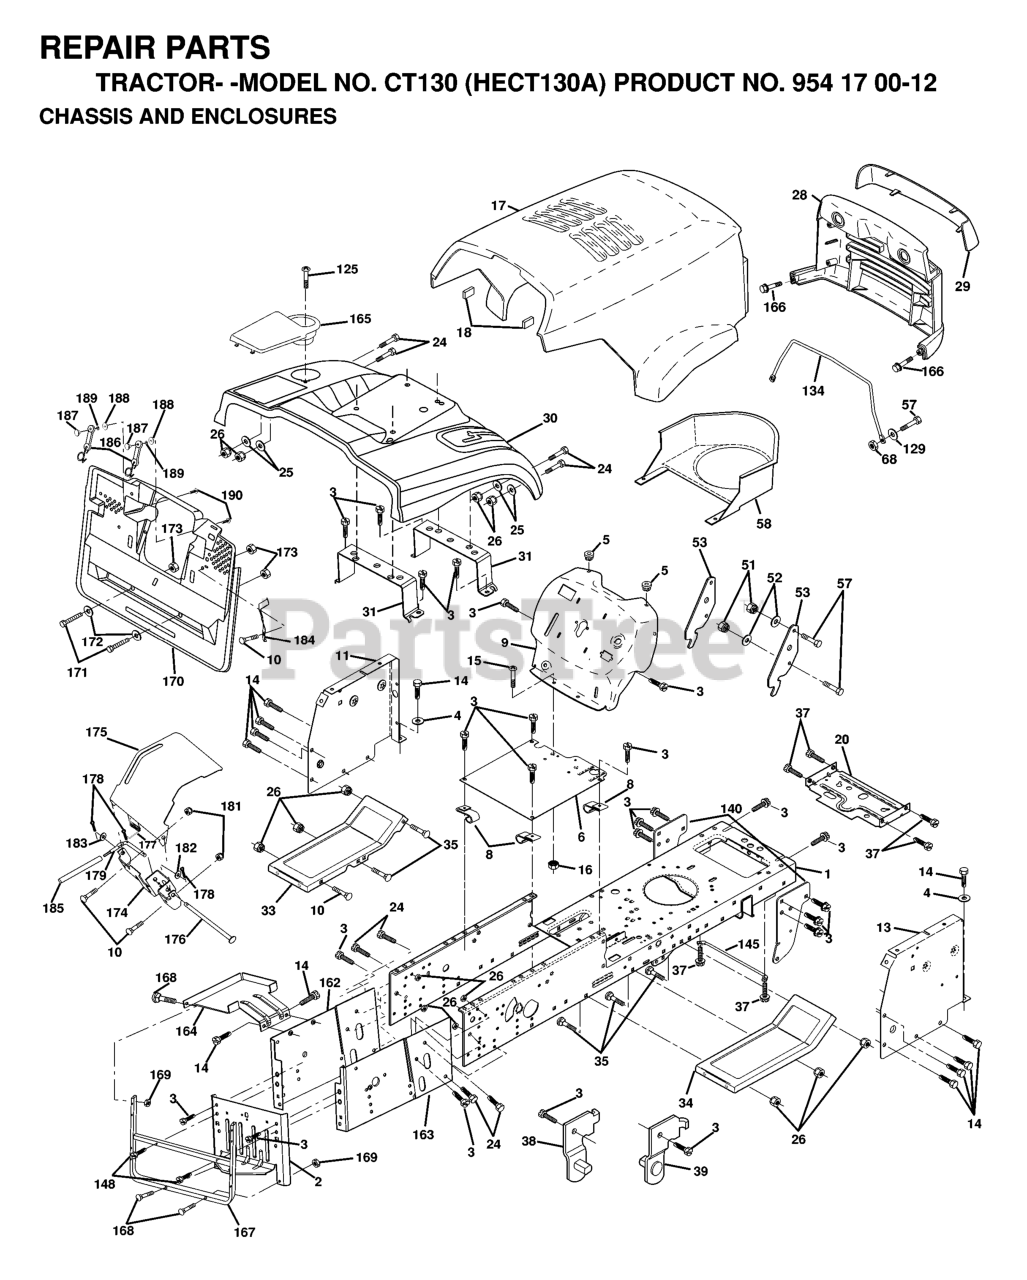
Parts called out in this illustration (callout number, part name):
3	SCREW
4	Washer 13/32 X 3/4 X 16 Ga.
5	BUMPER.RUBBER.HOOD
6	SADDLE FLAT
8	CLIP,INSULATOR
10	BOLT D
11	PANEL DASH LH
13	DASH PANEL
15	Screw, Machine, Truss Head 5/16-18 UNC x 3/4
16	NUT
17	HOOD
18	BUMPER HOOD T
20	PLATE MTG
25	WASHER
26	NUT
28	GRILL
29	LENS
31	BRACKET SUPPORT FENDER
33	FOOT REST LH
34	FOOTREST RH
37	Screw 5/16-18 x 1/2 Hex, Self Tapping 5/16-18 x 1/2
38	BRACKET LH PIVOT
39	BRACKET RH PIVOT
51	LOCKNUT.NYLOC.1/4-20
53	BRACKET PNT PICK OFF LT/PL
57	BOLT
58	AIR DUCT P/L/LT
68	NUT
125	SCREW.MACHINE.CR.1/4-20
134	ROD SUPPORT HOOD LT/PL HUS.
140	BRACKET SUSPENSION FRONT
145	ROD PIVOT CHASSIS/HOOD
148	SCREW
165	COVER BATTERY
166	SCREW
167	SUPPORT.ASM.BACKPLATE
168	BOLT.ROUND.HEAD.SQUARE.NECK
169	NUT T
170	COVER BACKPLATE
171	Bolt, 3/8-16 x 1-3/4
172	WASHER
176	HINGE PIN
177	SPRING COVER LH
178	COTTER PIN
180	BOLT RB
181	LOCKNUT
183	WASHER
185	TUBE LEVER
186	LATCH ASSY
187	WELDNUT
189	LOCKWASHER #10
190	SCREW
